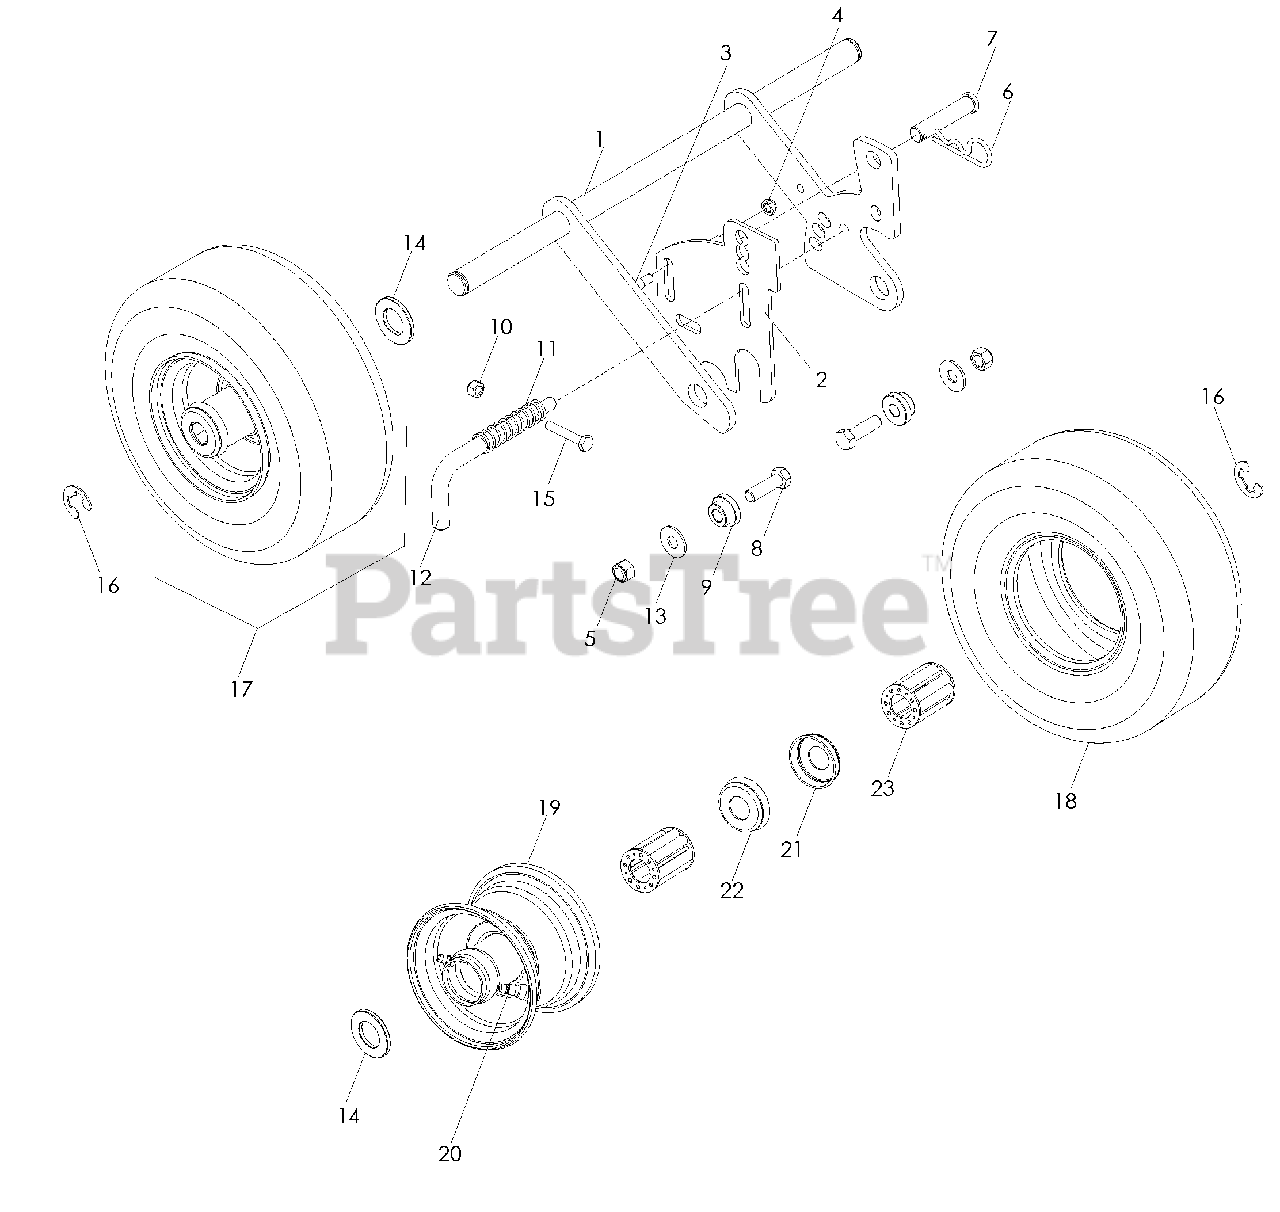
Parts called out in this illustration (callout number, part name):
1	AXLE, REAR
2	PLATE, SLIDE
3	BOLT 5/16 x 5/8
4	NUT 1/4-20 HEX NYLOC
5	NUT 3/8-16 HEX NYLOC
7	PIN, CLEVIS 1/2 x 2 1/4
8	HCS 3/8-16 x 1 1/4
10	NUT 1/4-20 HEX NYLOC
11	SPRING, COMPRESSION
12	PIN, SPRING
13	WASHER 3/8 STD FLT
14	WASHER 3/4 FLAT SAE
15	HCS 1/4-20 x 1 1/2
16	E-RING 3/4
17	WHEEL ASSEMBLY
19	RIM ASSEMBLY
20	AIR VALV E
21	END CAP
22	END CAP, NOTCHED
23	BEARING, ROLLER
